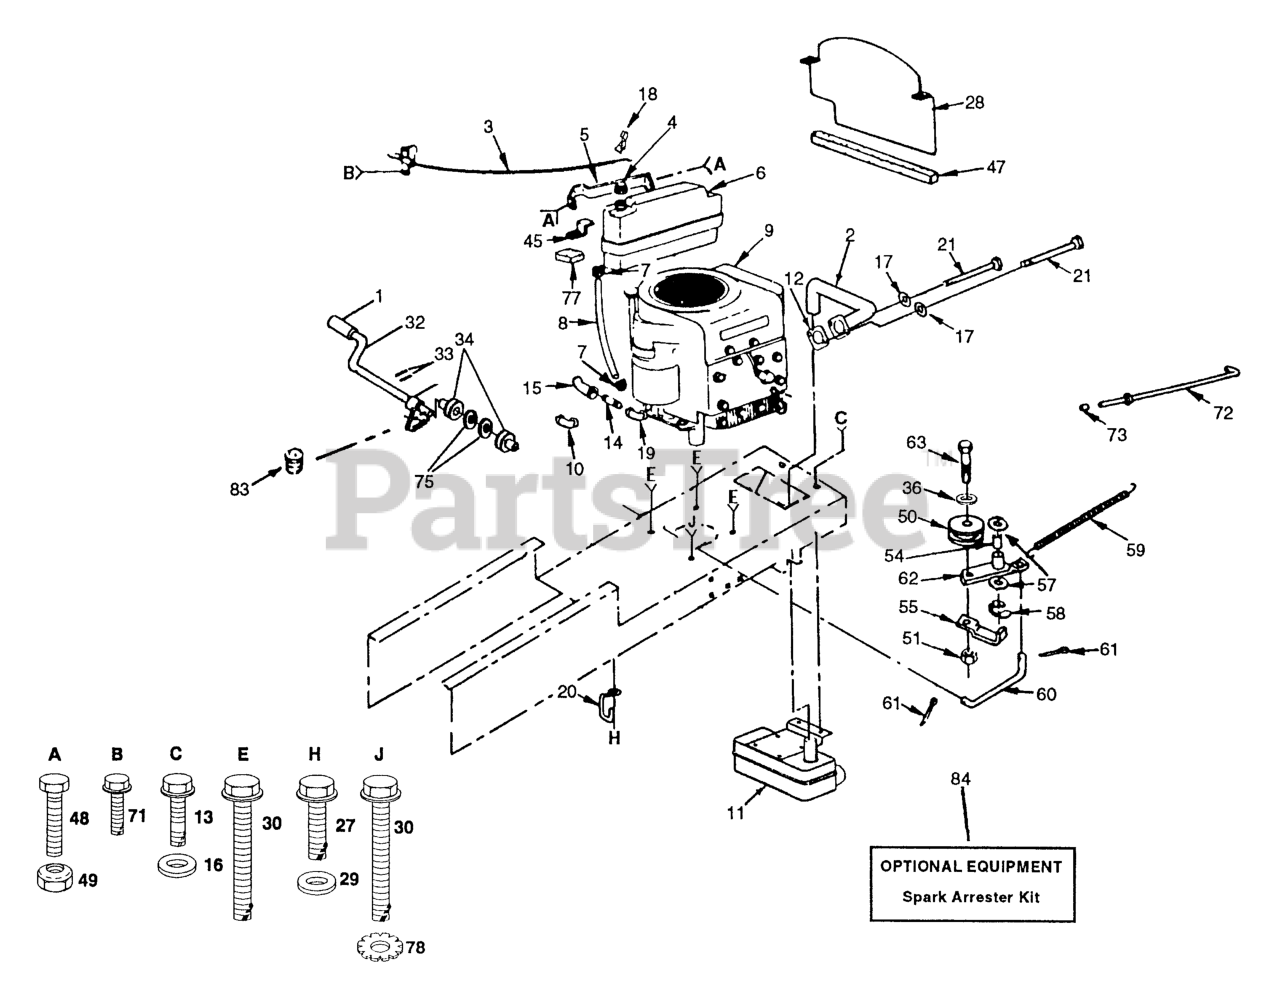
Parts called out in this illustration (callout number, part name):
1	COVER, PEDAL (1 2)
2	PIPE EXHAUST
3	THROTTLE CONTROL
4	FUEL CAP LT
5	SUPT TANK FUEL
6	FUEL TANK NLA
7	HOSE CLAMP
8	HOSE T
9	Engine Briggs & Stratton
10	STREET ELBOW LT NLA
11	MUFFLER EUROPE
12	GASKET ENGINE
13	SCREW.THDROL.5/16-18X3/4.TTY
14	Nipple, Pipe 3/8-18 NPT x 3"
15	ELBOW
16	Washer 11/32 x 1-1/4 x 16 Ga.
17	WASHER.LOCK.HVY.HLCL.SPR.5/16
18	THROTTLE STOP
19	STREET ELBOW LT
20	RETAINER-BELT LT
21	Screw, Hex.Hd. Cap 5/16 - 18 x 5/8
27	SCREW
28	BAFFLE,VERTICAL NLA
29	WASHER
30	SCREW
32	SHAFT FOOT PEDAL
33	DRIVE PIN
34	BEARING.NYLON
36	WASHER
45	BRACE-TANK LT
47	FOAM-STRIP LT
48	BOLT.FIN.HEX.5/16-18X3/4
49	LOCKNUT
50	IDLER PULLEY
54	BEARING LT (2 2)
55	RETAIN BELT
59	SPRING, RETURN LT
60	LINK, CLUTCH LT
61	COTTER PIN
62	ARM IDLER
63	BOLT
71	SCREW LT
72	BRAKE PARK ROD
73	PLUNGER CAP
75	WASHER LT
77	PAD-SPACER T
78	LOCKWASHER
83	Oil Drain Plug
84	SPARK ARREST
